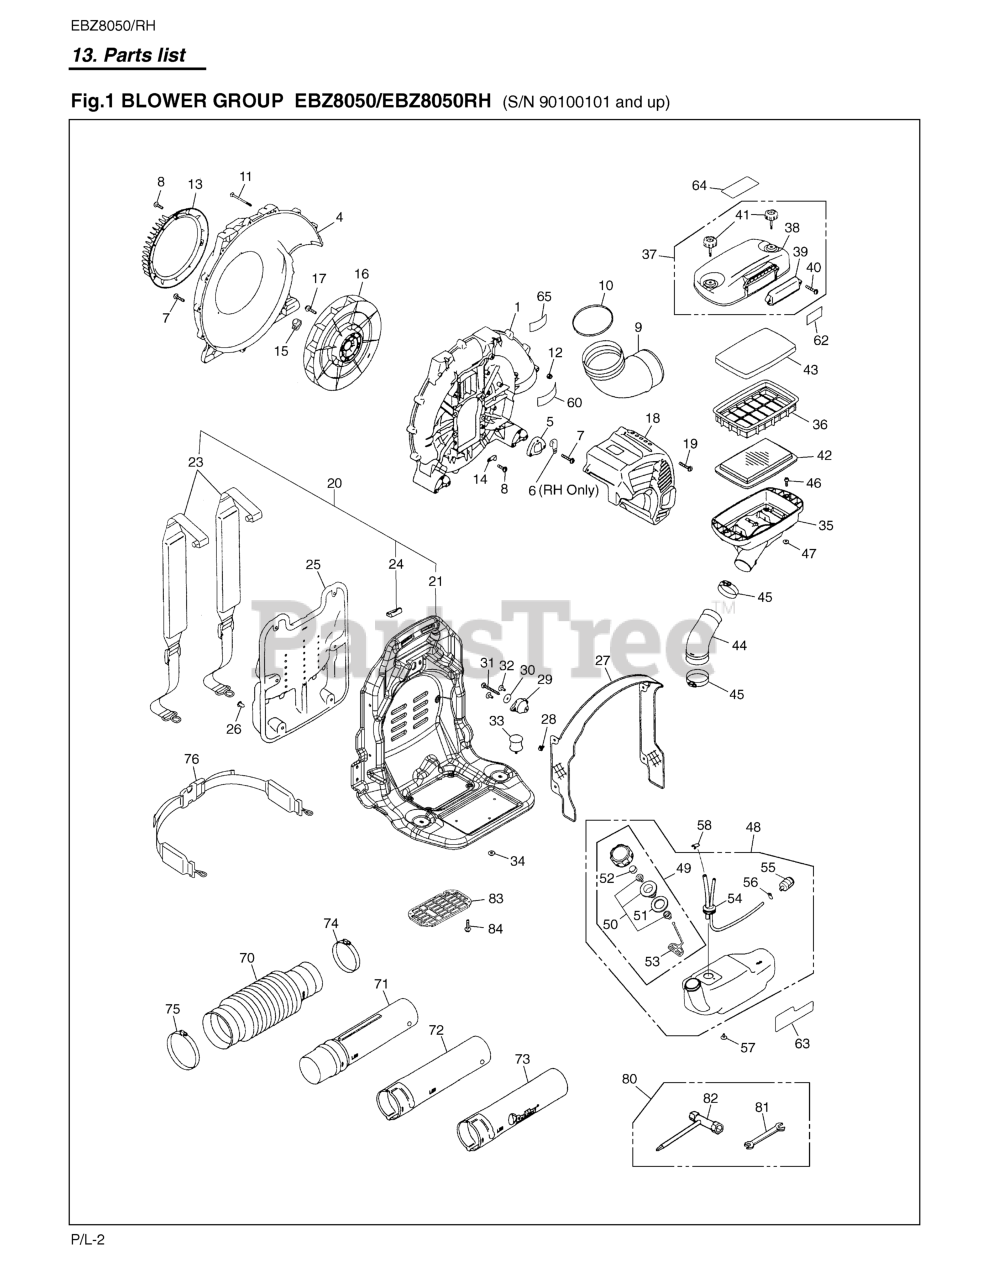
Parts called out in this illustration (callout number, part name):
1	VOLUTE CASE (REPLACES -55A3)
4	VOLUTE COVER
6	CLAMP (RH ONLY)
7	SCREW
9	ELBOW (RPLS 848L5855C0/C1)
10	O-RING
11	SCREW TORX
12	NUT
13	COVER, INLET (REPLACES -55D3)
14	CLAMP
15	CAP
16	FAN (REPLACES 848-L58-5212)
17	BOLT
18	Engine Cover
19	SCREW
20	FRAME ASSY
21	FRAME
23	BAND ASSY
24	CLIP
25	PAD
26	CLIP
27	NET COMP
28	CLIP
29	DAMPER, UPPER
30	WASHER
31	BOLT, TORX
32	SCREW TORX
33	DAMPER, LOWER
34	NUT, M6
35	BODY, CLEANER
36	CASE, INNER
37	COVER ASSY
38	COVER
39	COVER
40	SCREW
41	KNOB BOLT
42	ELEMENT (PAPER)
43	ELEMENT (FOAM) (RPLS -82320)
44	HOSE
46	BOLT TORX
47	NUT
48	TANK ASSY
49	CAP ASSY
50	HOLDER ASSY
51	PACKING
52	FILTER
54	PIPE COMP
55	FILTER ASSY
56	CLIP
57	SCREW TORX
58	CLIP
60	LABEL CE CAUTION
64	LABEL
65	LABEL, SOUND
70	HOSE
71	SWIVEL JOINT
72	PIPE, STRAIGHT
73	PIPE, END
76	BAND ASSY
80	TOOL-SET
81	SPANNER
83	NET
84	CLIP
